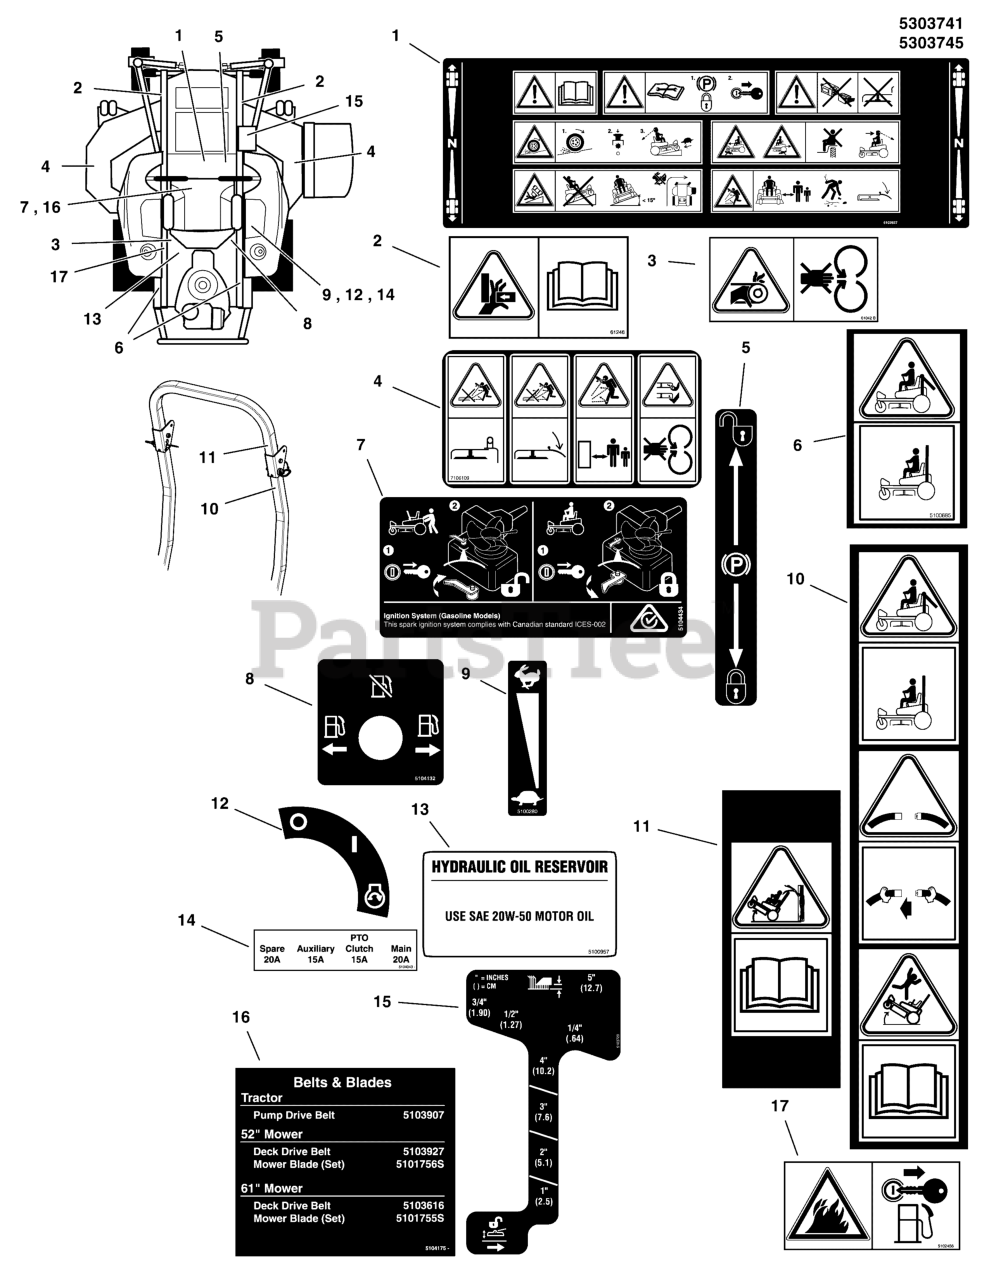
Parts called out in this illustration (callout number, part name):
1	DECAL, MAIN SAFETY, ANSI CE
2	DECAL, PINCH POINT, CE
3	DECAL, CE DANGER
4	DECAL, DISCHARGE SAFETY, EXPORT
5	DECAL, PARKING BRAKE SYMBOLS
6	DECAL, WARNING, ROLLBAR, CE
7	DECAL, TRANSAXLE RELEASE, ZT440
8	DECAL, FUEL VALVE
9	DECAL, THROTTLE CONTROL
10	DECAL, SAFETY, CE ROPS
11	DECAL, SAFETY, CE ROPS, OBS
12	DECAL, IGNITION SWITCH
13	DECAL, HYDRAULIC OIL, SAE 20W50
14	DECAL, FUSE LOCATION, IS2100
15	DECAL, CUT HEIGHT, IS700/ZTS700
16	DECAL, BELT & BLADE, IS2100Z (V2)
17	DECAL, FIRE ANSI EXPORT
